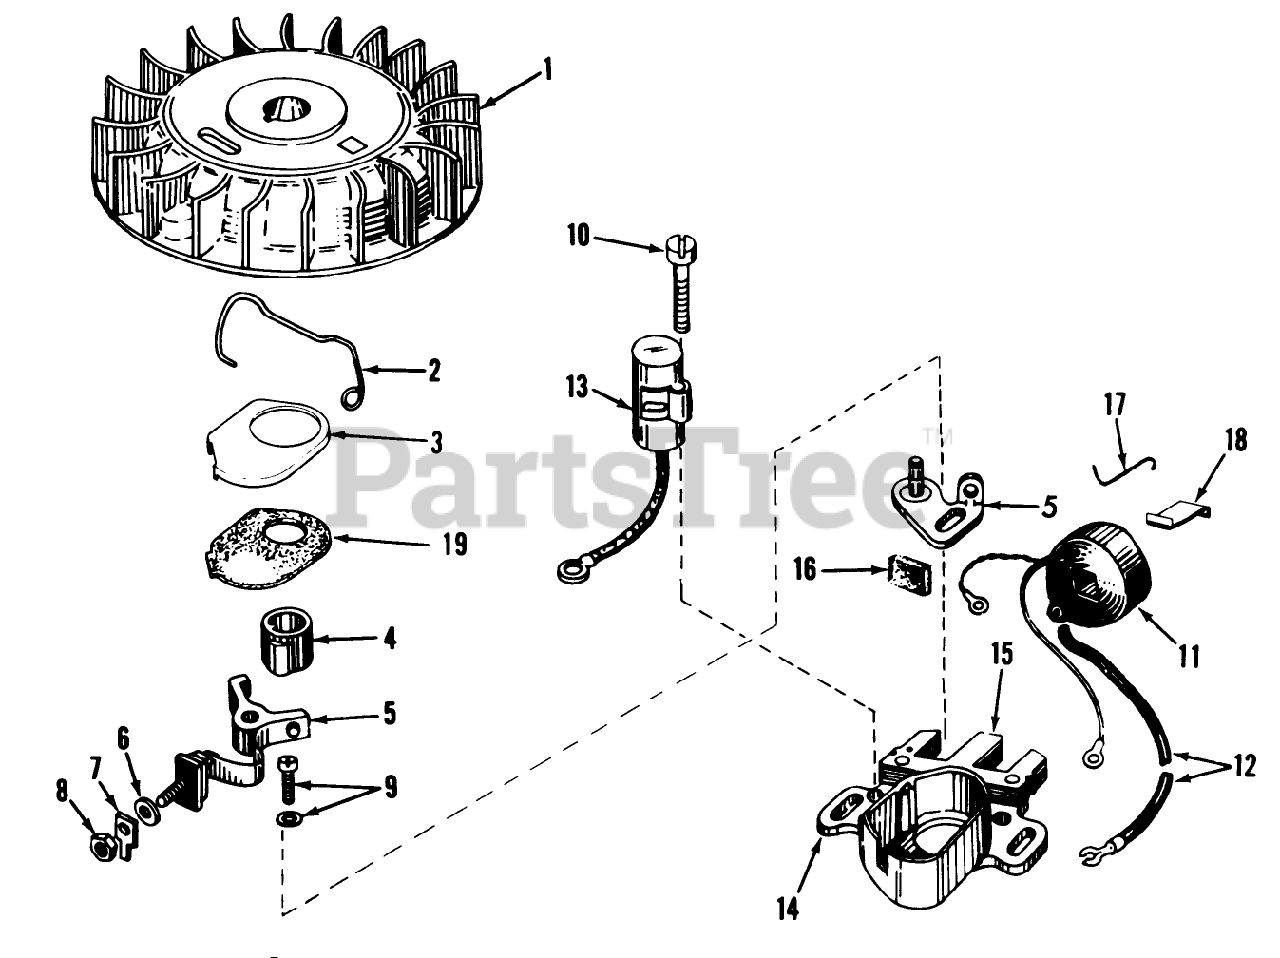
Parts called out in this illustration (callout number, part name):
1	NUT-LOCK, NI
2	THRUST WASHER
3	BEARING-NEEDLE
4	NUT-LOCK, NI
5	SCREW-HH
7	REAR AXLE WA
8	NUT-LOCK, NI
11	FITTING-GREASE
13	SCREW-HH
14	SCREW-HH
15	WASHER-FLAT
16	RING-RETAINING
17	WASHER-THRUST
22	BEARING-CUP, TAPERED
23	NUT-HEX, SLOTTED
24	PIN-COTTER
25	CAP-DUST
26	WASHER-FLAT
27	BEARING-CONE, TAPERED
30	NUT-HEX,SLOTTED
32	SCREW-HH
34	NUT-HEX JAM LH
36	NUT-JAM
38	REAR STRG TUBE *PP
39	PIVOT ARM WA
